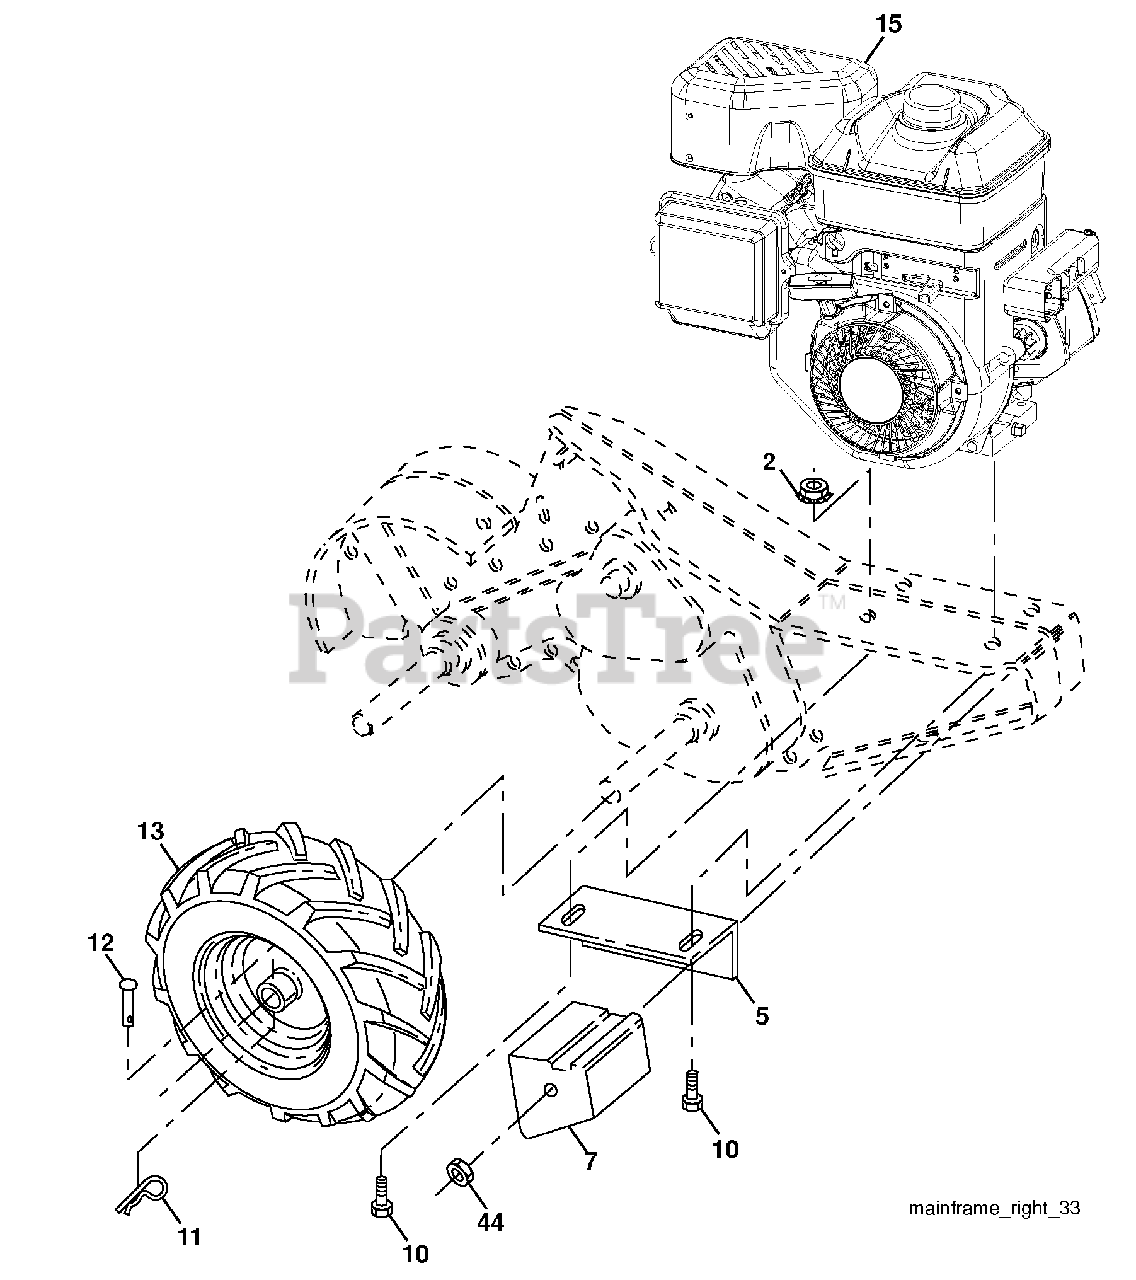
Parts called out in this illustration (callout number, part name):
2	Locknut, Hex, Flange 5/16-18
5	Bracket, Reinforcement R.H.
7	Counter Weight, R.H.
10	Bolt, Hex 5/16-18 x 1-1/2
11	Clip, Hairpin
12	Rivet, Drilled
44	Nut Keps Hex 3/8-16 unc
